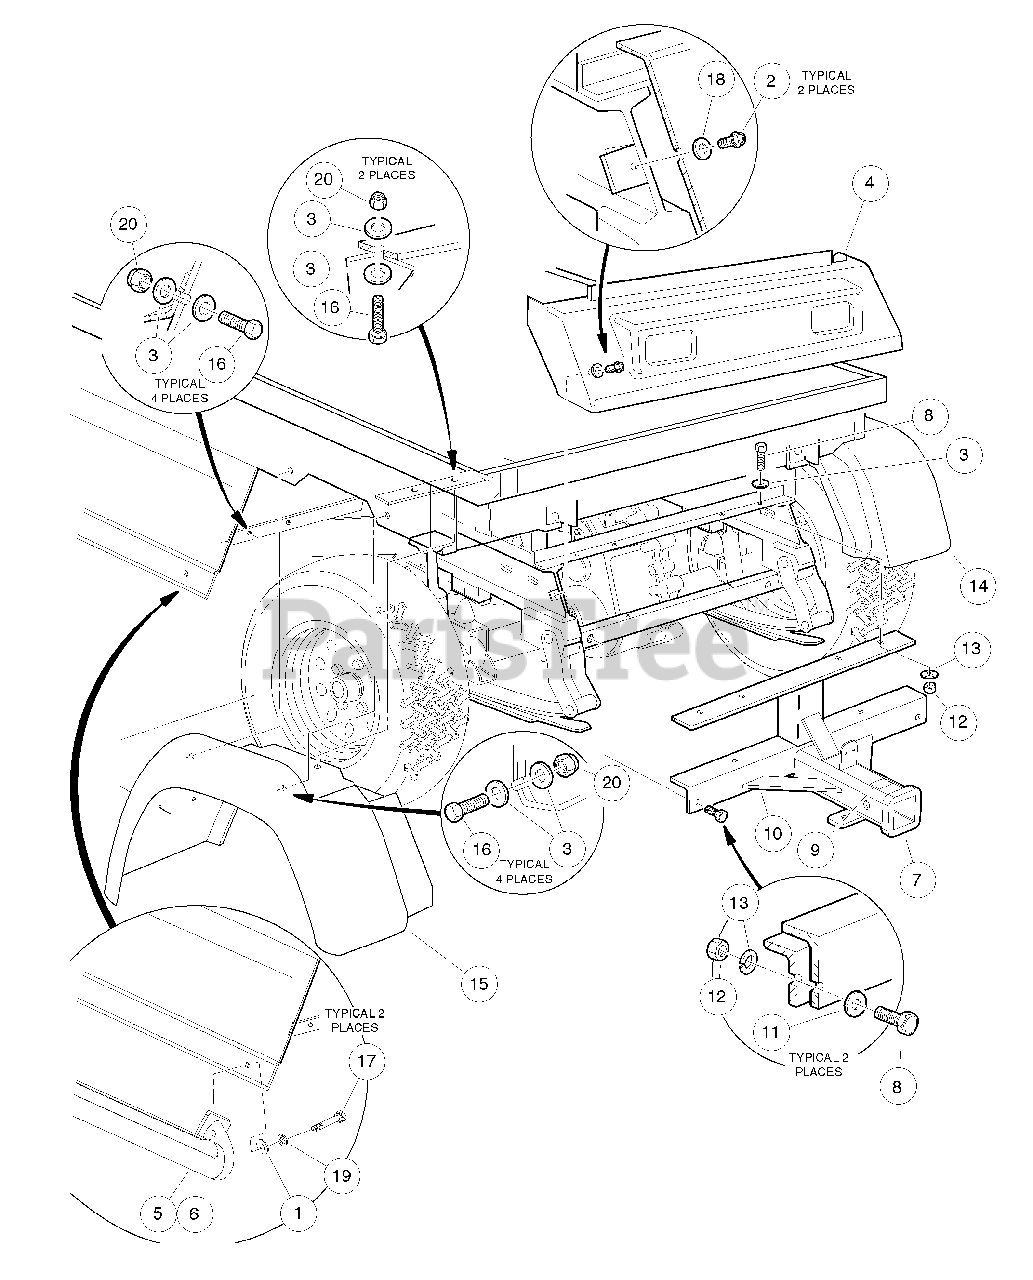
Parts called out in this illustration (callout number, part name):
1	Washer, 3/8 Flat
2	Screw, 1/4 X 0.625 Hex-Head
3	Washer, 1/4" Type B Flat
5	Side Step Bar
6	Side Step Bar
7	Kit, Rear Receiver
8	Screw, 5/16-18 X 1.00 Hex Cap
9	Decal, Trailer Hitch
10	Receiver Hitch Weld Asm
11	Washer, 5/16 Type A Flat
12	Nut, 5/16-18 Hex
13	Lockwasher, 5/16 Split
14	Fender, Right Rear
15	Fender, Left Rear
16	Screw, 1/4-20 X 1.0 Hex-Head Cap
17	Screw, 3/8-16 X 1.00 Hex-Head Cap
18	Washer, 1/4 Type A Narrow Flat
19	Washer, Lock, Hel Sp 3/8 Reg
20	Locknut, 1/4-20 Nylon Insert
